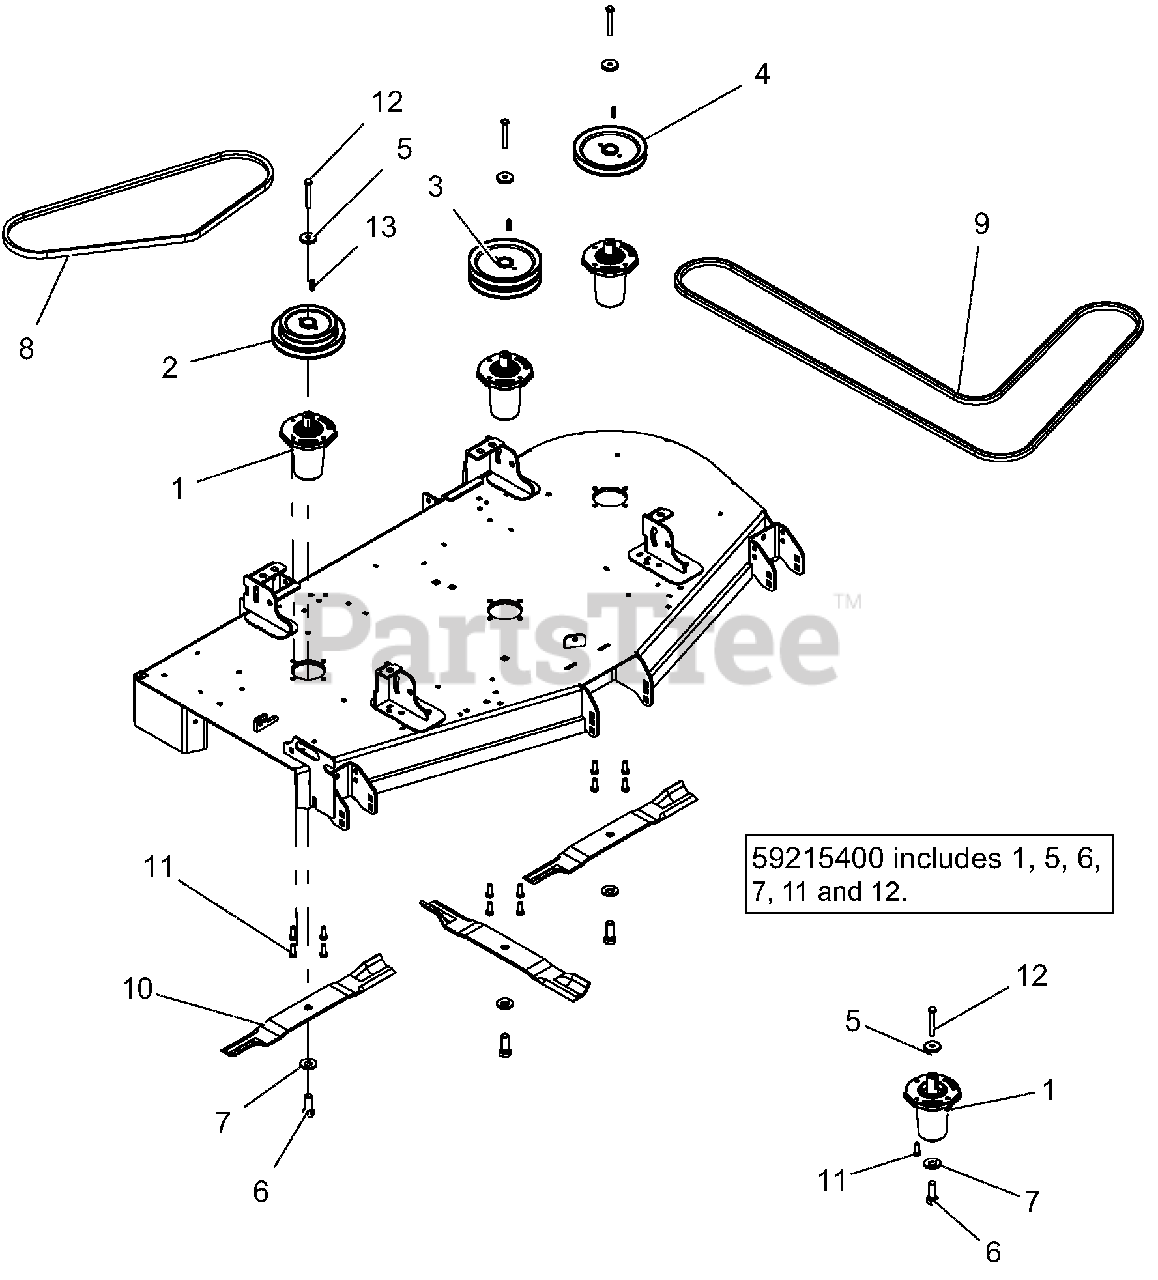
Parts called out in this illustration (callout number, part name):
1	SERVICE, ASM SPINDLE- DUCTILE
2	PULLEY, DOUBLE -1" ID X 6.75" & 5.25" OD
3	PULLEY, DOUBLE 1"ID X 6.75"OD-BLACK
4	PULLEY, V-1" ID X 6.75" OD-BLACK
5	RETAINER, SHEAVE SPINDLE
6	BLT, HEX .62-18X1.75 GR8 YWZC
7	WSHR, BLVL .63X1.625X.14
8	BELT, B 63.00 RAW COGGED
9	BELT, BB 133.00 WRAPPED HEX
10	BLADE, MOWER 60"
11	BLT-HEX .38-16X1.00 GR5 YWZC EP30
12	BLT-HEX .38-16X2.75 GR8 YWZC
13	KEY-SQ .250X.250X1.00 RC 40-50
